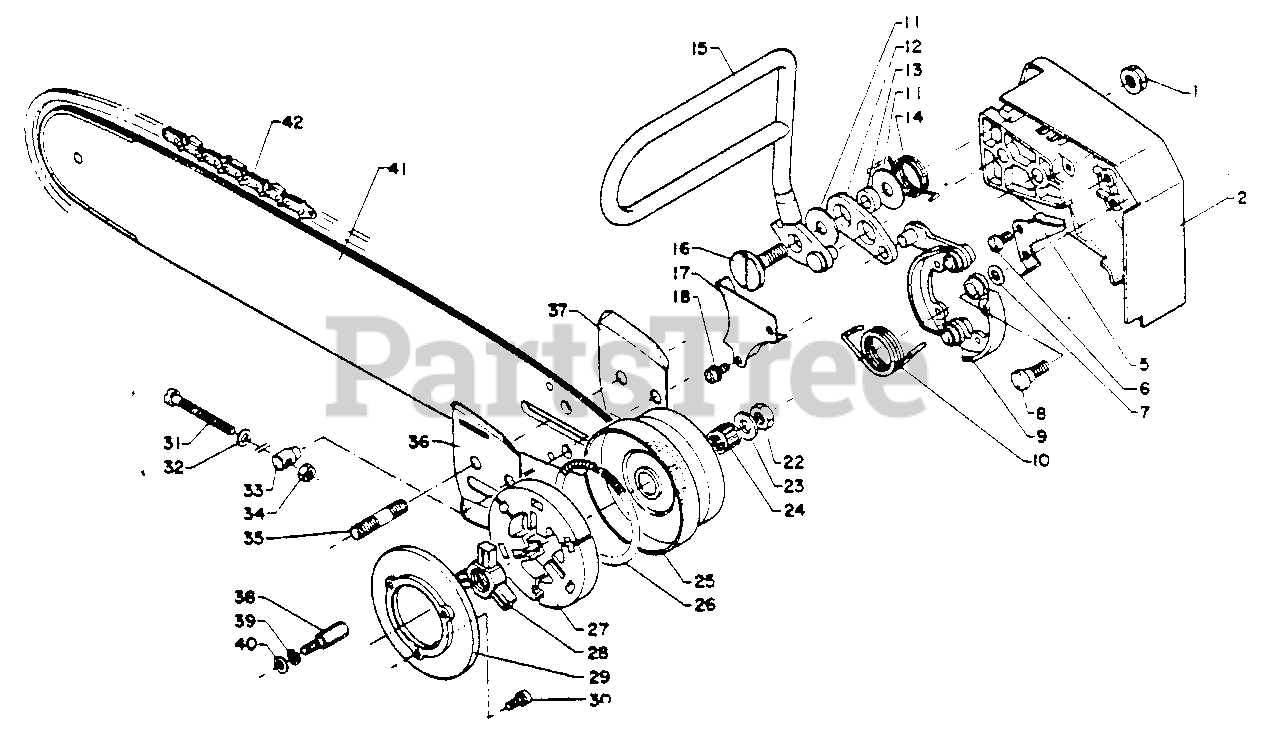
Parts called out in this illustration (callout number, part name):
1	NUT - FLANGE
2	COVER, GUIDE BAR
5	GUIDE, BRAKE SHOE
6	SCREW - 5X8
7	WASHER - 6
9	SHOE, BRAKE
10	SPRING
11	SPACER
12	CONNECTOR
13	SPACER
14	SPRING, RETURN
15	HANDLE, BRAKE
17	SEAL, DUST
18	SCREW - 4X10
22	LOCKNUT
23	WASHER
24	BEARING, NEEDLE
25	DRUM, CLUTCH
26	SPRING, CLUTCH
27	SHOE, CLUTCH
28	HUB, CLUTCH
29	SEAL, DUST
30	SCREW - 4X10
31	SCREW, TENSIONER
32	WASHER - 5
33	TENSIONER, CHAIN
34	LOCKNUT - 5
35	STUD, GUIDE BAR
36	PLATE, GUIDE - INNER
37	PLATE, GUIDE - OUTER
38	CATCHER, CHAIN
39	LOCKWASHER - 5
40	WASHER - 5
41	GUIDE BAR - 16" (40cm)
41	GUIDE BAR - 40" (101cm)
42	SAW CHAIN -- 72D-59E
42	SAW CHAIN -- 72LP-60E
